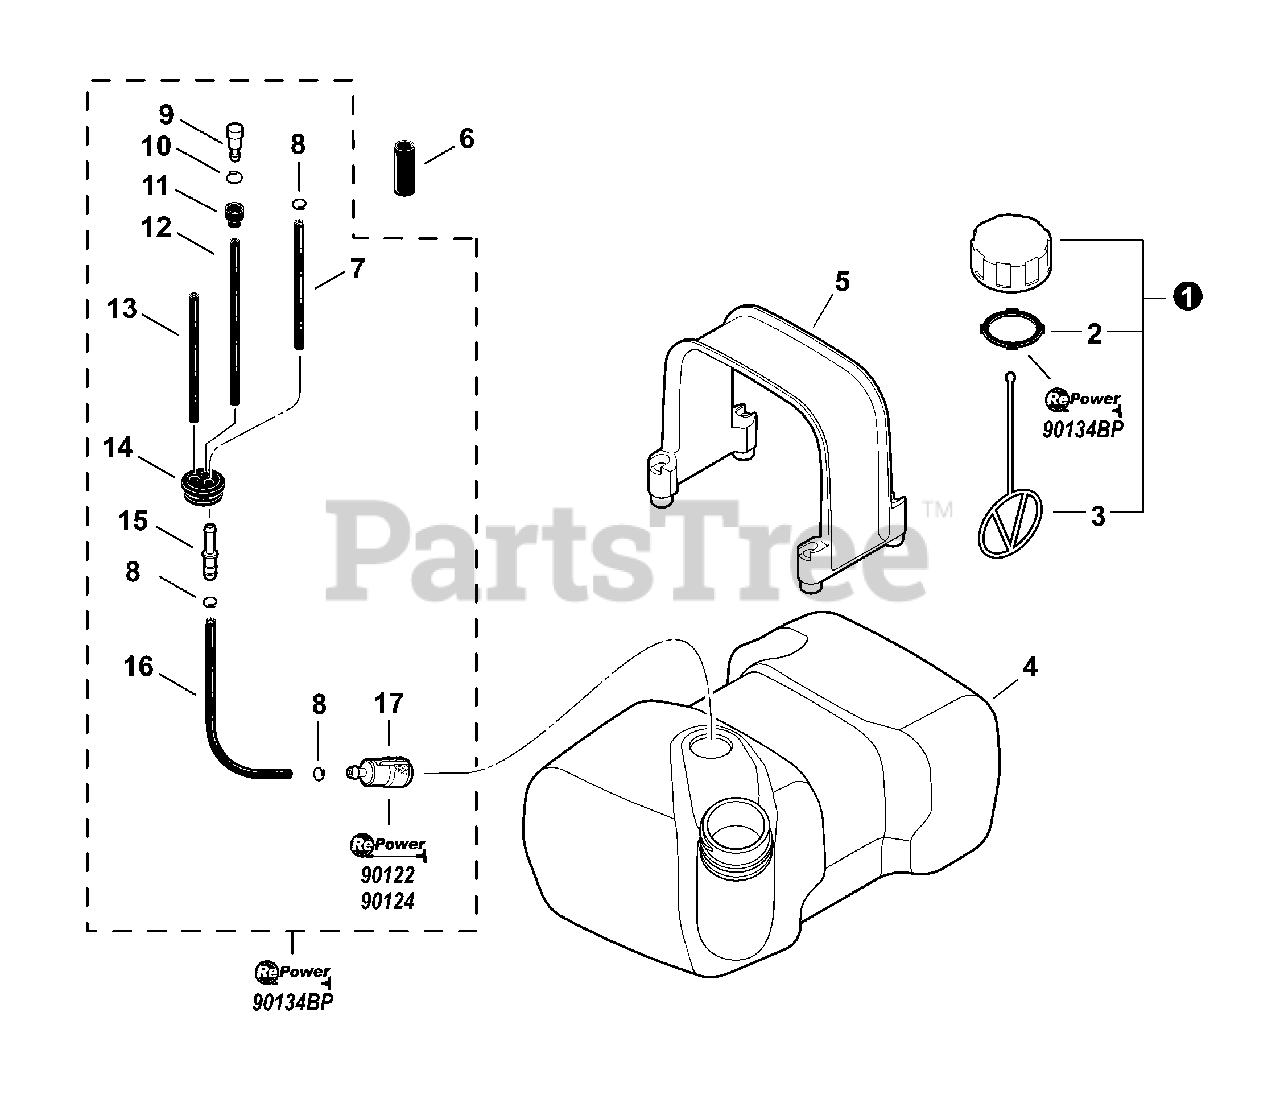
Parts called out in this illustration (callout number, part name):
1	CAP ASSY - ORANGE
2	GASKET, CAP
3	CONNECTOR, CAP
4	TANK, FUEL
5	RETAINER, FUEL TANK
6	SLEEVE
7	PIPE - 3×5×135 -- BLACK
8	CLIP - 6
9	VENT, FUEL TANK
10	CLIP - 6.5
11	COVER, VENT
12	PIPE - 3×6×130 -- BLACK
13	PIPE - 2.4×5×200 -- BLACK
14	GROMMET
15	CONNECTOR, FUEL PIPE
16	PIPE, FUEL - BLACK
17	FILTER, FUEL
